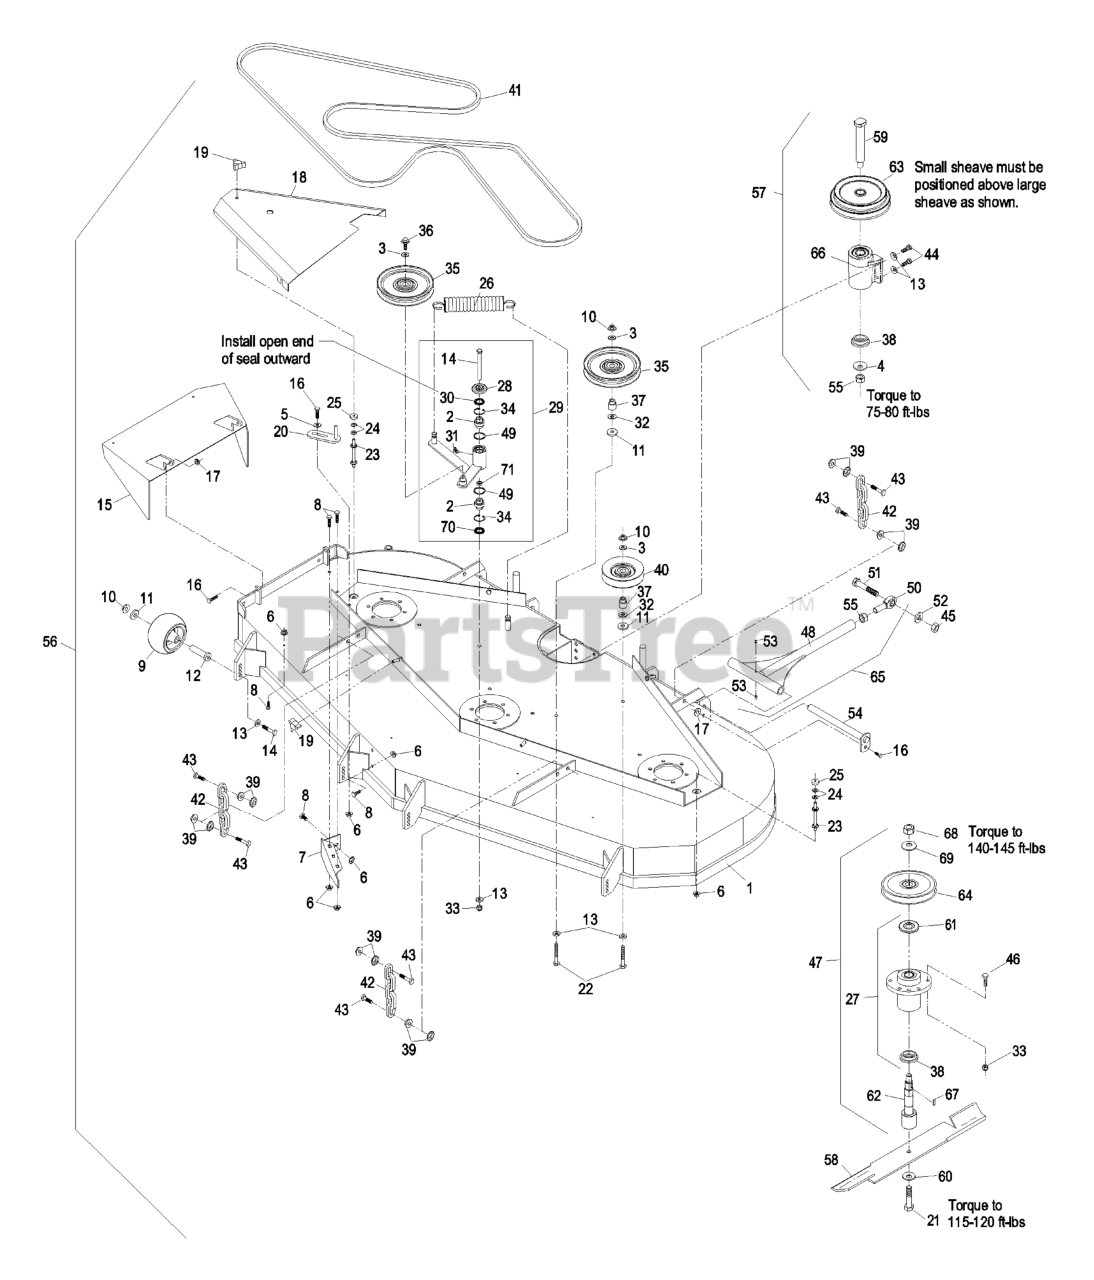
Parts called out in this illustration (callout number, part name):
1	ASM,DECK W/DECALS LZ/XP72
2	BEARING-SPHERICAL
3	WASHER-FLAT
4	WASHER-SPRING
5	WASHER-SPRING
7	WLD,BAFFLE DISCHARGE
8	SCREW-HH
9	ROLLER-SCALP, ANTI
10	NUT-HHF, WHIZ
12	BUSHING-ROLLER
13	WASHER-BELLEVILLE
14	SCREW-HH
15	WLD,CHUTE 72
16	SCREW-HH
17	NUT-LOCK, NI
18	SHIELD,BELT RH
19	KNOB-3 PRONG
20	GUIDE-BELT
21	SCREW-CAP
22	SCREW-HH
23	STUD-SHIELD, BELT (SHORT)
24	WASHER-FLAT
28	GUARD-TOP
29	KIT,DECK IDLER LZ/XP
30	SEAL-LIP, SINGLE
31	FITTING-GREASE, 90 DEG
32	WASHER-FLAT
33	NUT-LOCK, NI
34	RING-SNAP
36	SCREW-HHF
37	BUSHING-IDLER
38	SPACER-GUARD, BOTTOM
40	PULLEY-IDLER
41	BELT-V
42	CHAIN-LIFT, DECK
43	SCREW-HH
44	SCREW-HH
45	NUT-HEX
46	SCREW-HH
50	BALLJOINT-SPHERICAL
51	SCREW-HH
52	WASHER-LOCK
53	FITTING-GREASE
54	PIN-STRUT
55	NUT-HEX
56	Asm, Deck Complete
57	KIT,JACKSHAFT 60/72-3750
59	JACKSHAFT
60	WASHER-BLADE BOLT, HEAVY
61	GUARD-BEARING, TOP
62	SPINDLE,SHORT
63	SHEAVE, JACKSHAFT DOUBLE
64	SHEAVE,BLADE DRIVE 7.5
65	STRUT WLDMT S/A
70	SEAL-LIP, DOUBLE
